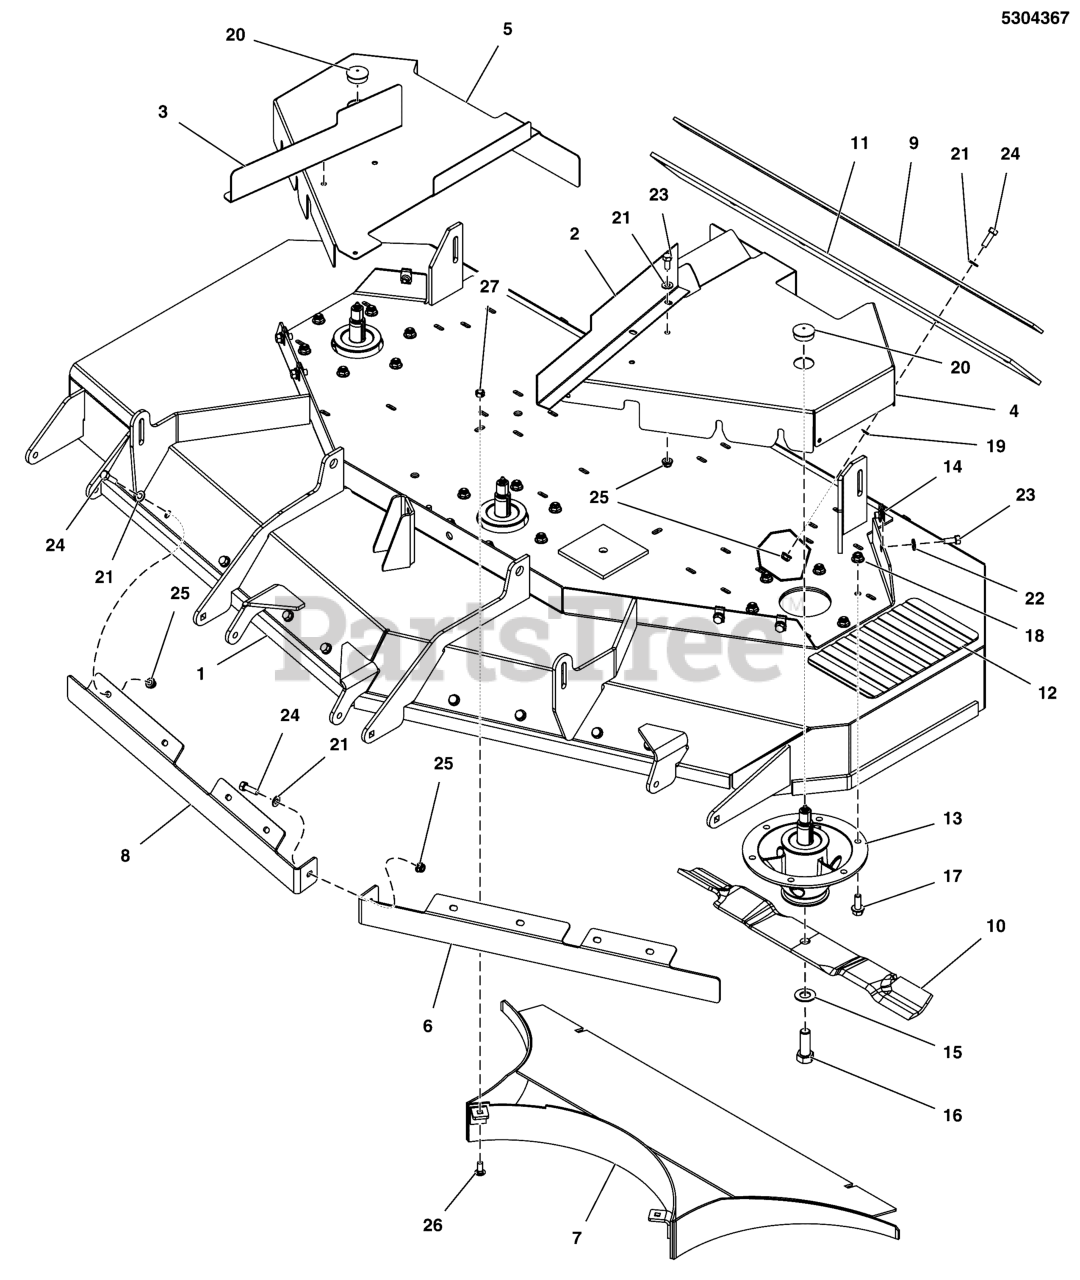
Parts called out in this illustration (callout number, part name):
1	DECK SHELL W/DECALS,61RDCE,2100,5414783B
2	PLATE, DECK GUARD, SHIELD, 61, LH - RED
3	PLATE, DECK GUARD, SHIELD, 61, RH - RED
4	PLATE, DECK GUARD, 61, LH - RED
5	PLATE, DECK GUARD, 61, RH - RED
6	BAFFLE, BLOWOUT, 61 iCD, LH - RED
7	WELD, REAR BAFFLE, 61RD, SHRT - BLK
8	BAFFLE, BLOWOUT, 61 ICD, RH - RED
9	PLATE, SUPPORT - BLK
10	BLADE SET, MULCH, 61 DECK
11	FLAP, STRIPER, 52 DECK
12	SAFETY WALK, 9.75 X 6.00
13	SPINDLE, ASSM, CAST IRON - 8.0
14	BODY CLIP, 5/16-18-7GA MATERIAL
15	WASHER, BLADE BOLT, 9/16" F436, CZ
16	BOLT, 5/8-11 X 1-3/4 GD8
17	BOLT, 3/8-16 X 1, FLANGE, GD 5, CZ
18	NUT, 3/8-16 HEX NYLOCK FLANGE
19	5/16 PUSH-ON NUT RETAINER, STL, CZ
20	PLUG, PANEL, 1.25 - BLACK
21	WASHER, 5/16" SAE
22	WASHER, 5/16 F436 FLAT
23	BOLT, 5/16-18 X 3/4 GD5
24	BOLT, 5/16-18 X 1 GD5 CZ
25	NUT, 5/16-18 HEX NYLOCK FLANGE
26	BOLT, 5/16-18 X 3/4, CARRIAGE
27	NUT, 5/16-18, HEX, CNTR LK,ZINC PHOS/OIL
